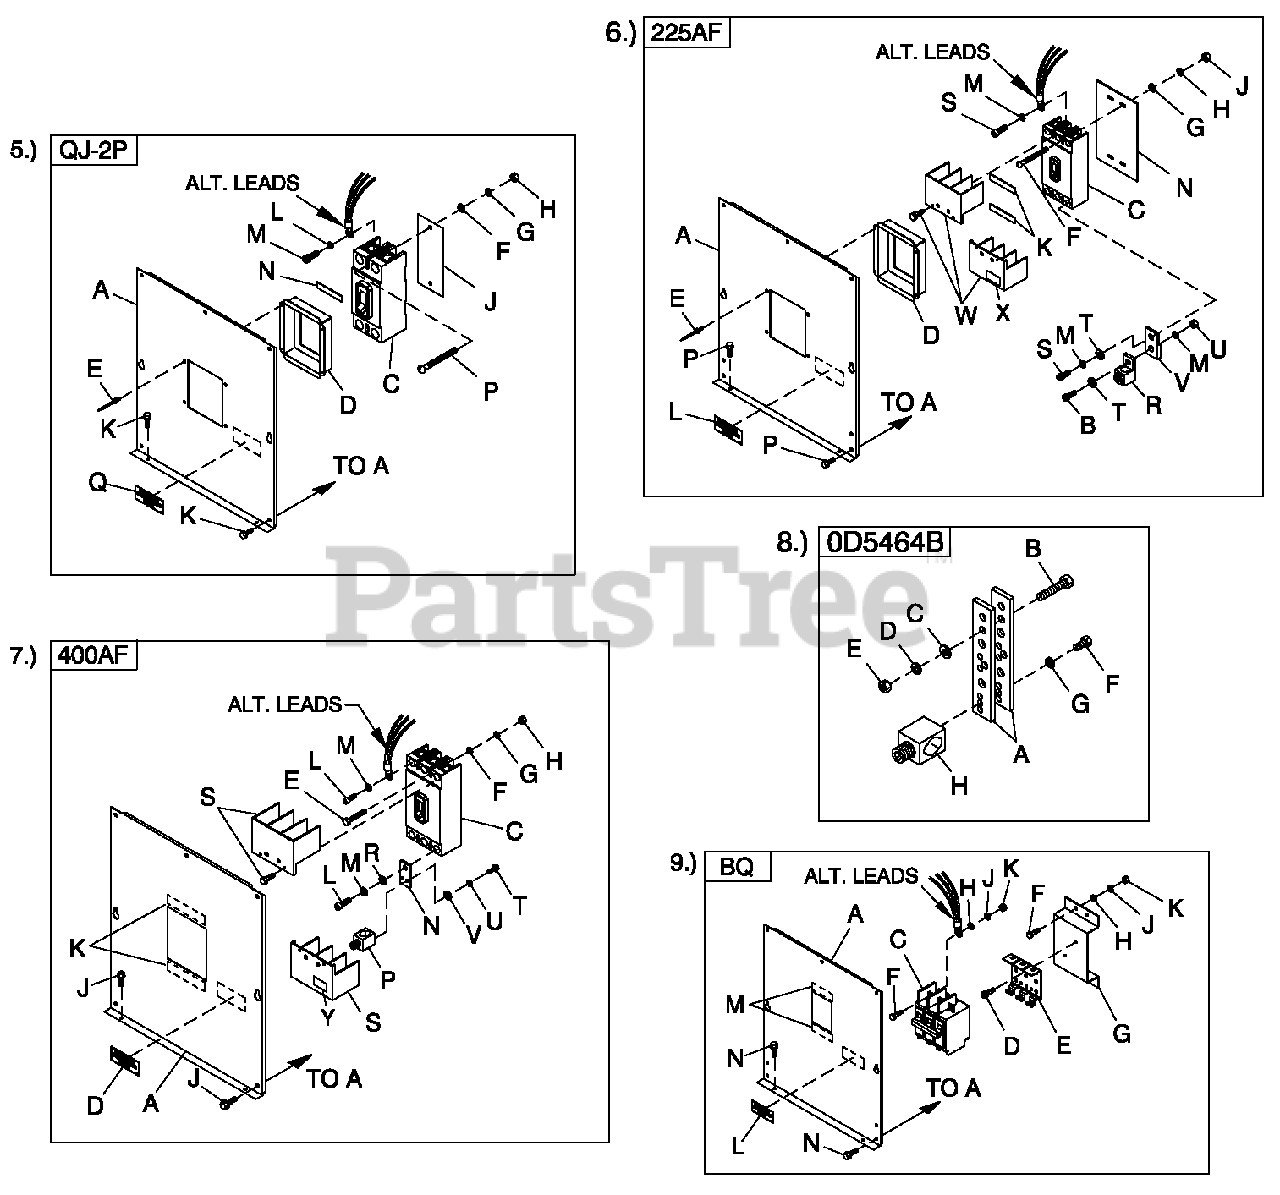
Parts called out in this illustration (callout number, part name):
9	UL CIRCUIT BREAKER (BQ)
A	COVER QJ 2P FRM CB
C	CB 0225A 240V 2P S QJ22
D	COVER QJ 2P CB DISH
E	RIVET POP .125 X .275 SS
F	WASHER FLAT 1/4-M6 ZINC
G	WASHER LOCK M6-1/4
H	NUT HEX 1/4-20 STEEL
J	INSUL CB 2P QJ
K	SCREW THF M6-1 X 16 N WA Z/JS
L	WASHER LOCK 3/8
M	SCREW SHC 3/8-16 X 3/4 G8.8 NZ
N	TAPE ELEC 1/2 FOAM (AS REQ'D)
P	SCREW RHM 1/4-20 X 3
Q	DECAL CUSTOMER CONNECT INSIDE
A	COVER CB C2-C4 (225AF)
B	SCREW SHC M8-1.25 X 25 G12.9
C	CIRCUIT BREAKERS 200A FRAME (3P)
D	COVER CB DISH 225AF (3P)
F	SCREW RHM #8-32 X 3-1/4
G	WASHER FLAT #8 ZINC
H	WASHER LOCK #8-M4
J	NUT HEX #8-32 STEEL
K	TAPE ELEC 1/2 FOAM
L	DECAL CUSTOMER CONNECT INSIDE
M	WASHER LOCK M8-5/16
N	INSULATOR CB 225AF (3P)
P	SCREW THF M6-1 X 16 N WA Z/JS
R	LUG SLDLSS 300 MCM-6 AL/CU
S	SCREW SHC M8-1.25 X 20 G8
T	WASHER FLAT 5/16-M8 ZINC
U	NUT HEX M8-1.25 G8 CLEAR ZINC
V	BUS BAR 200A LUG ADAPTOR
W	TERMINAL COVER CB
X	DECAL TERMINAL SHOCK HZD BI
A	COVER CB C2-C4 400AF
C	CIRCUIT BREAKERS 400A FRAME
D	DECAL CUSTOMER CONNECT INSIDE
E	SCREW RHM 10-32 X 4
F	WASHER FLAT #10 ZINC
G	WASHER LOCK #10
H	NUT HEX #10-32 STEEL
J	SCREW THF M6-1 X 16 N WA Z/JS
L	SCREW SHC M10-1.5 X 25 G12.9
M	WASHER LOCK M10
N	BUS BAR CB ADAPTER 225-400 A
P	LUG SLDLSS 600/250-1/0 X 1/4-28
S	TERM COVER CB
T	SCREW HHC 1/4-28 X 1/2 G5
U	WASHER LOCK M6-1/4
V	WASHER FLAT 1/4-M6 ZINC
Y	DECAL TERMINAL SHOCK HZD BI
A	BUS BAR NEUTRAL BLOCK 390
B	SCREW HHC M8-1.25 X 45 G8.8 FT
C	WASHER FLAT 5/16-M8 ZINC
D	WASHER LOCK M8-5/16
E	NUT HEX M8-1.25 G8 YEL CHR
F	SCREW HHC 1/4-28 X 3/4 G5
G	WASHER LOCK 1/4-M6 SS
H	LUG SLDLSS 600/250-1/0 X 1/4-28
A	COVER BQ CIR BREAKER CPL 3P
C	CB 0125A 2P 240V S BQ2 LL
D	SCREW PHTT M4-0.7 X 10 ZYC
E	BRKT CB MTG BACK
F	SCREW RHM #10-32 X 3/4
G	BRKT BQ CB STANDOFF
H	WASHER FLAT #10 ZINC
J	WASHER LOCK #10
K	NUT HEX #10-32 STEEL
M	TAPE ELEC 1/2 FOAM
N	SCREW THF M6-1 X 16 N WA Z/JS
